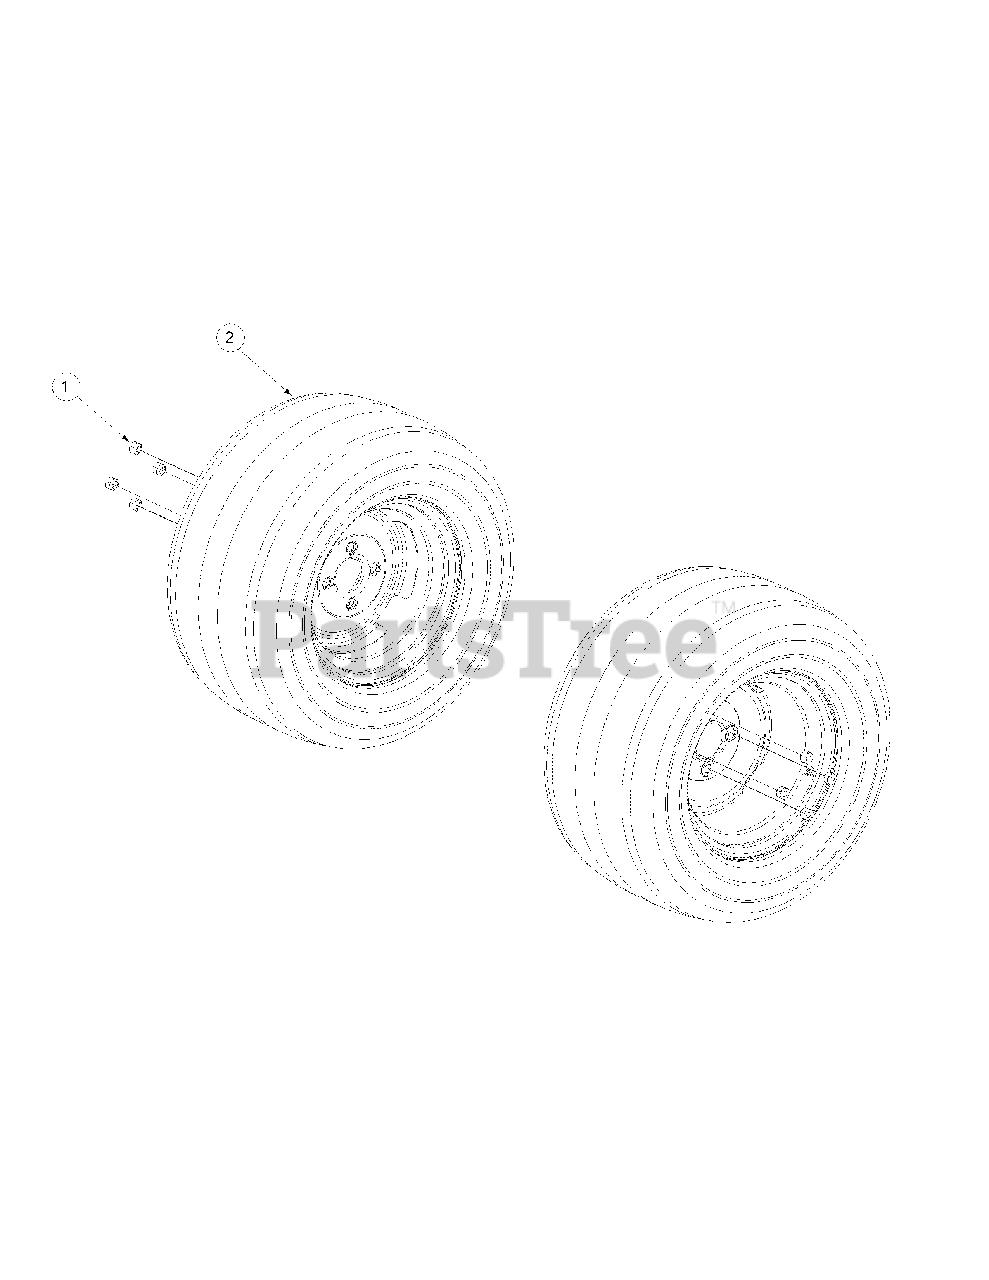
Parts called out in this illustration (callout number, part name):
1	Lug Nut, 1/2-20
2	Wheel Assembly, 24 x 12.00-12, Beige Includes:
2	Tire, 24 x 12.00-12,Turf Master; Rim, 12 Dia x 8.50 width
